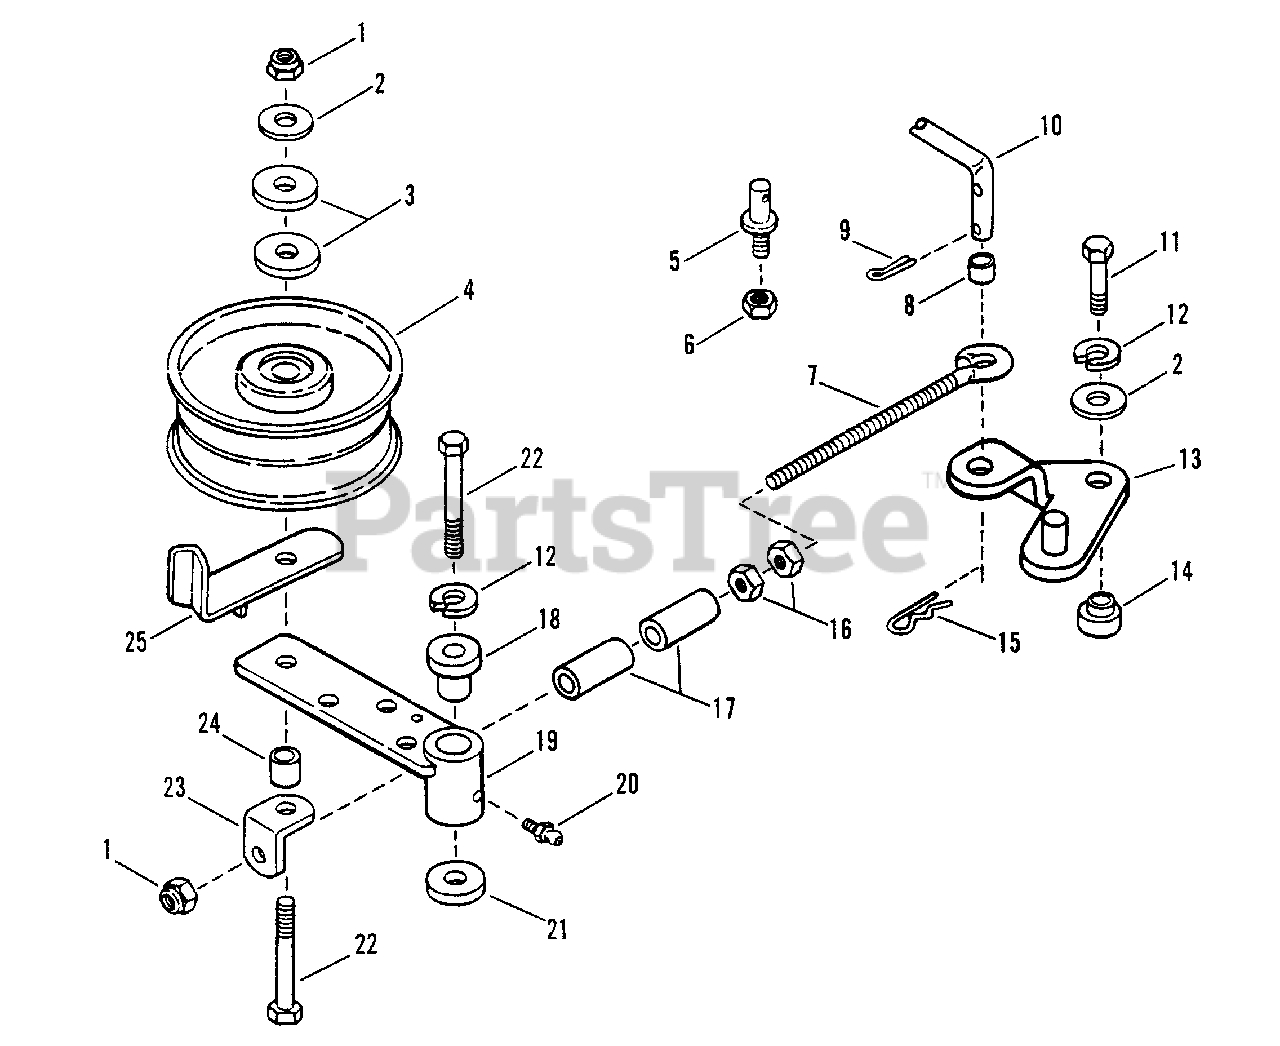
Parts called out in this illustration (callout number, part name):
1	NUT, 3/8 - 16 Nyloc
2	WASHER, 3/8" Flat
3	WASHER, Flat
4	PULLEY, Idler, 5.25 O.D.
5	STUD
6	NUT, 3/8 - 24 Lock
7	LINK STUD
8	LINKAGE SLEEVE
9	COTTER-PIN, 3/32 x 1"
10	LINK, Blade Engagement
11	SCREW, 3/8 - 16 x 1 1/2 HHC
12	WASHER, 3/8 Lock
13	LINK, Blade Engage Weldment
14	SPACER, Pivot
15	HAIR-PIN
16	NUT, 3/8 - 16
17	BUSHING
18	SPACER, Pivot
19	WELDMENT, Idler Arm
20	ZERK, 1/4 - 28
21	BUSHING
22	BOLT, 3/8 - 16 x 3" HHC
23	ANGLE, Blade Engagement
24	SPACER, Blade Linkage
25	GUIDE, Belt
